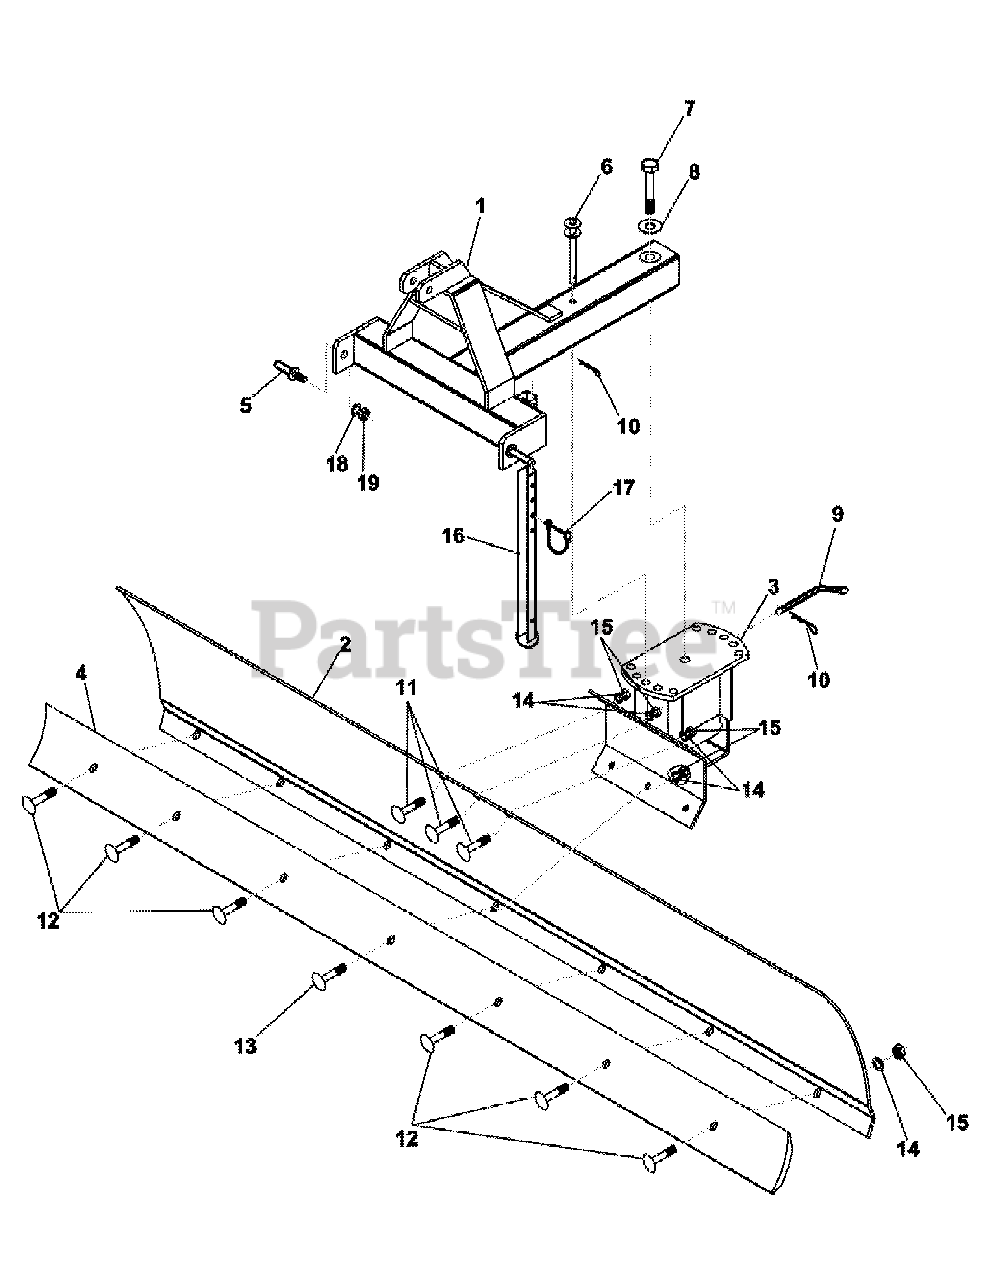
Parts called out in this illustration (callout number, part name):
1	A-Frame RB72 & RB84
1	A-Frame subcompact RB60
2	Mold board curved subcompact RB60
2	Mold board curved RB72
2	Mold board curved RB84
3	Swivel (curved mold board) RB72 & RB84
3	Swivel subcompact RB60
4	Scraper blade RB60
4	Scraper blade RB72
4	Scraper blade RB84
5	Hitch pin 7/8"x2"
6	Swivel pin RB72 & RB84
6	Swivel pin RB60
7	Hex bolt 1"x6" RB72 & RB84
7	Hex bolt 3/4"x5" RB60
8	Flat washer 1" RB72 & RB84
8	Flat washer 3/4" RB60
9	Bent pin RB72 & RB84
10	R clip Ø4
11	Hex bolt 5/8"-11x1.75" RB72 & RB84
11	Hex bolt 5/8"-11x1.50" RB60
12	Plow bolt 5/8"-11x1.75"
13	Plow bolt 5/8"x2"
14	Lock washer 5/8"
15	Hex nut 5/8"
16	Foot stand
17	Lock pin
18	Lock washer 7/8"
19	Hex nut 7/8"
